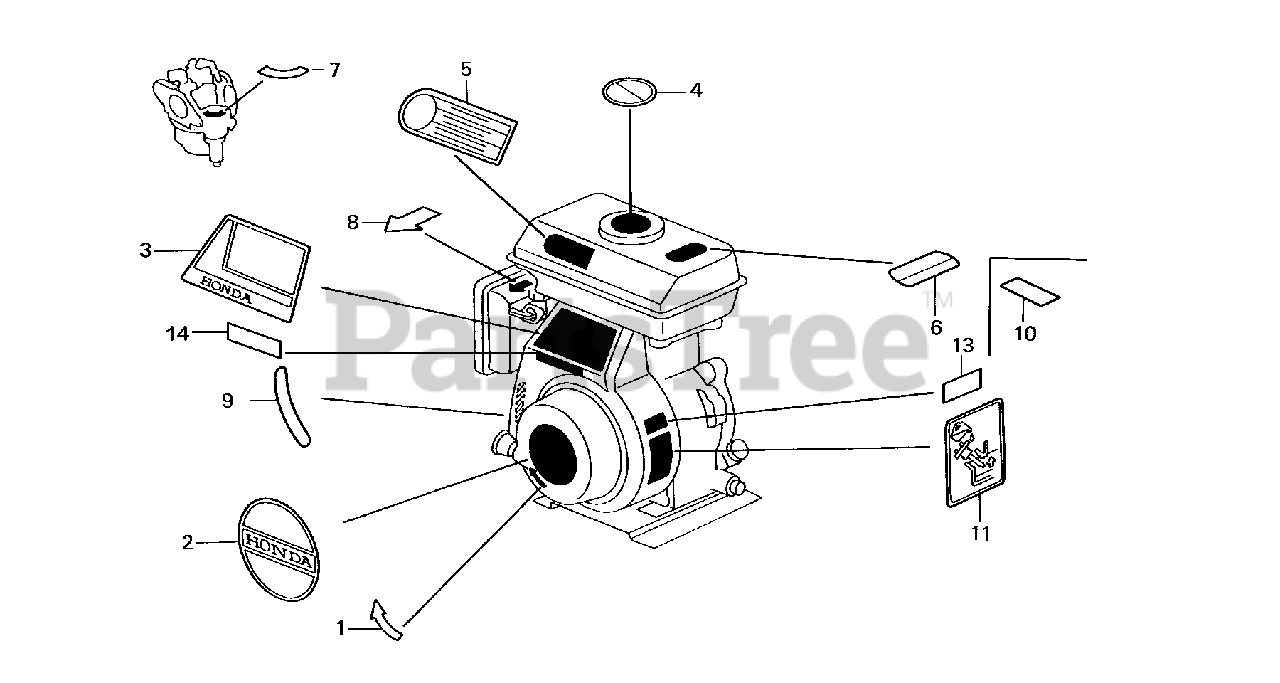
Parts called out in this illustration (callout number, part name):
2	EMBLEM (EXP)
2	EMBLEM
4	MARK, CAUTION (EXTERNAL)
7	MARK (EXTERNAL)
8	MARK, CHOKE
9	MARK, THROTTLE (ENGLISH/FRENCH)(GERMAN)
10	LABEL, FUEL CAUTION
